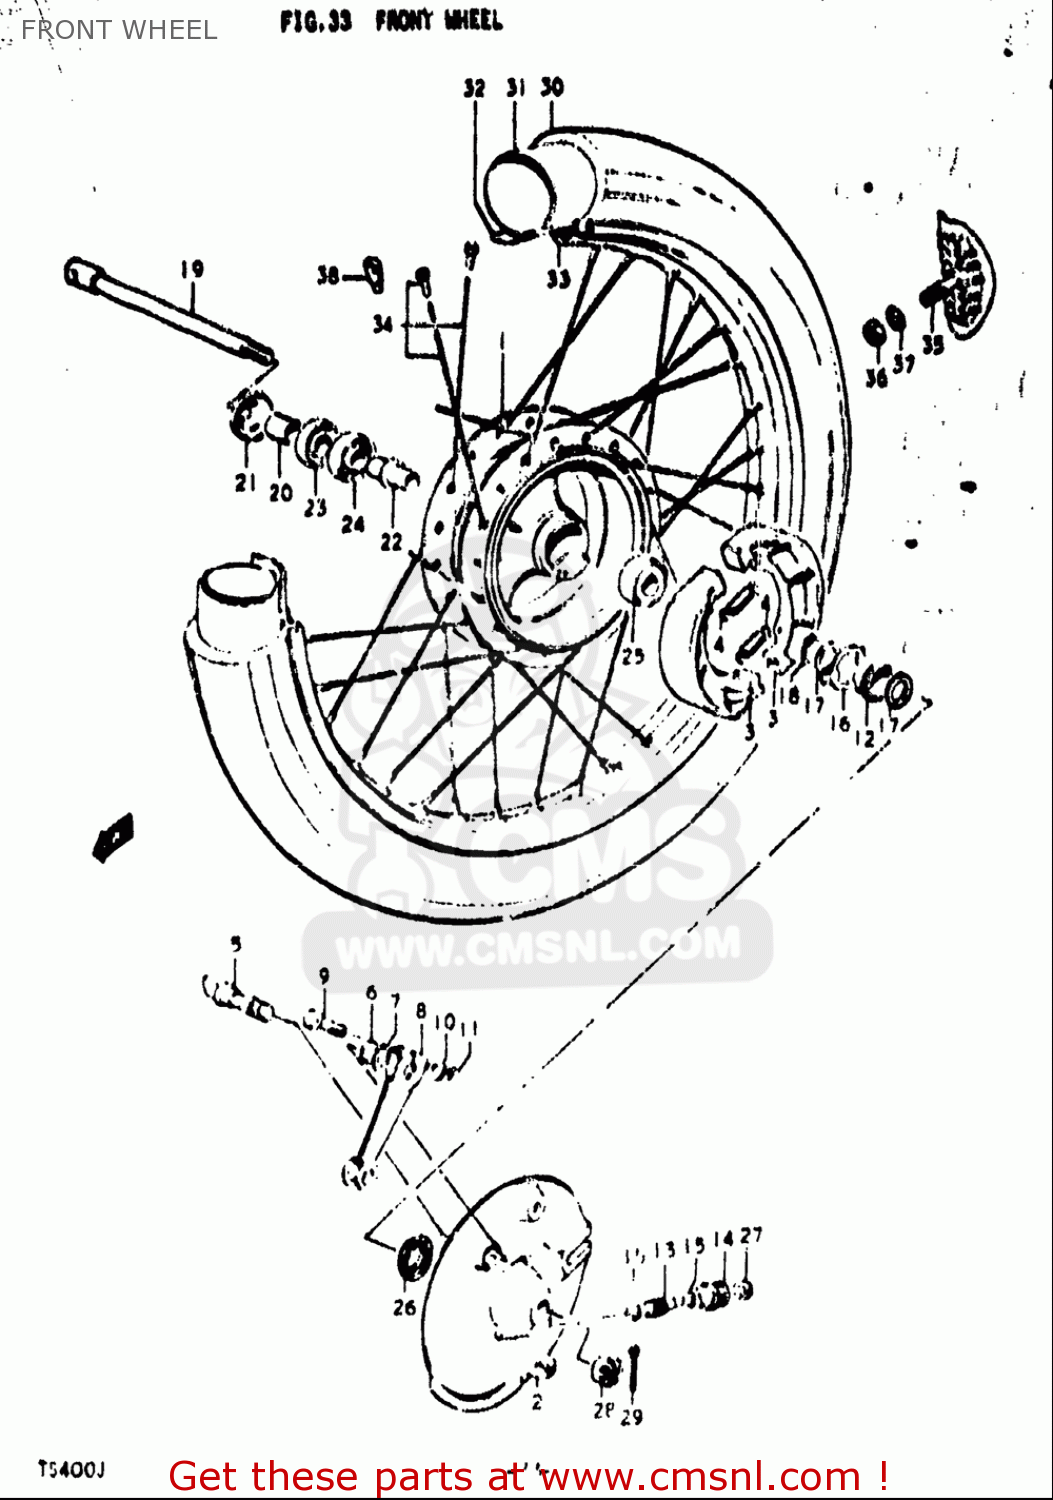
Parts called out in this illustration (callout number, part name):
1	HUB,FRONT
4	SPRING,BRAKE SHOE
6	O RING(D:2.4,ID:14.8)
7	WASHER(15.5X24X1.6)
9	BOLT
10	WASHER
11	NUT
13	PINION,SPEEDOMETER
14	BUSHING,SPEEDOMETER PINION
15	WASHER(5.1X9X0.4)
16	DRIVER,SPEEDOMETER GEAR
17	WASHER(22.5X27X1)
18	CIRCLIP
20	SPACER
24	BEARING
25	BEARING
26	SEAL,OIL(26X38X4)
27	SEAL,OIL(6X10X3)
28	NUT
29	PIN
31	TUBE ASSEMBLY,WHEEL,INNER
32	PROTECTOR,WHL INR TUBE
37	WASHER
38	BALANCER,WHEEL (50G)
